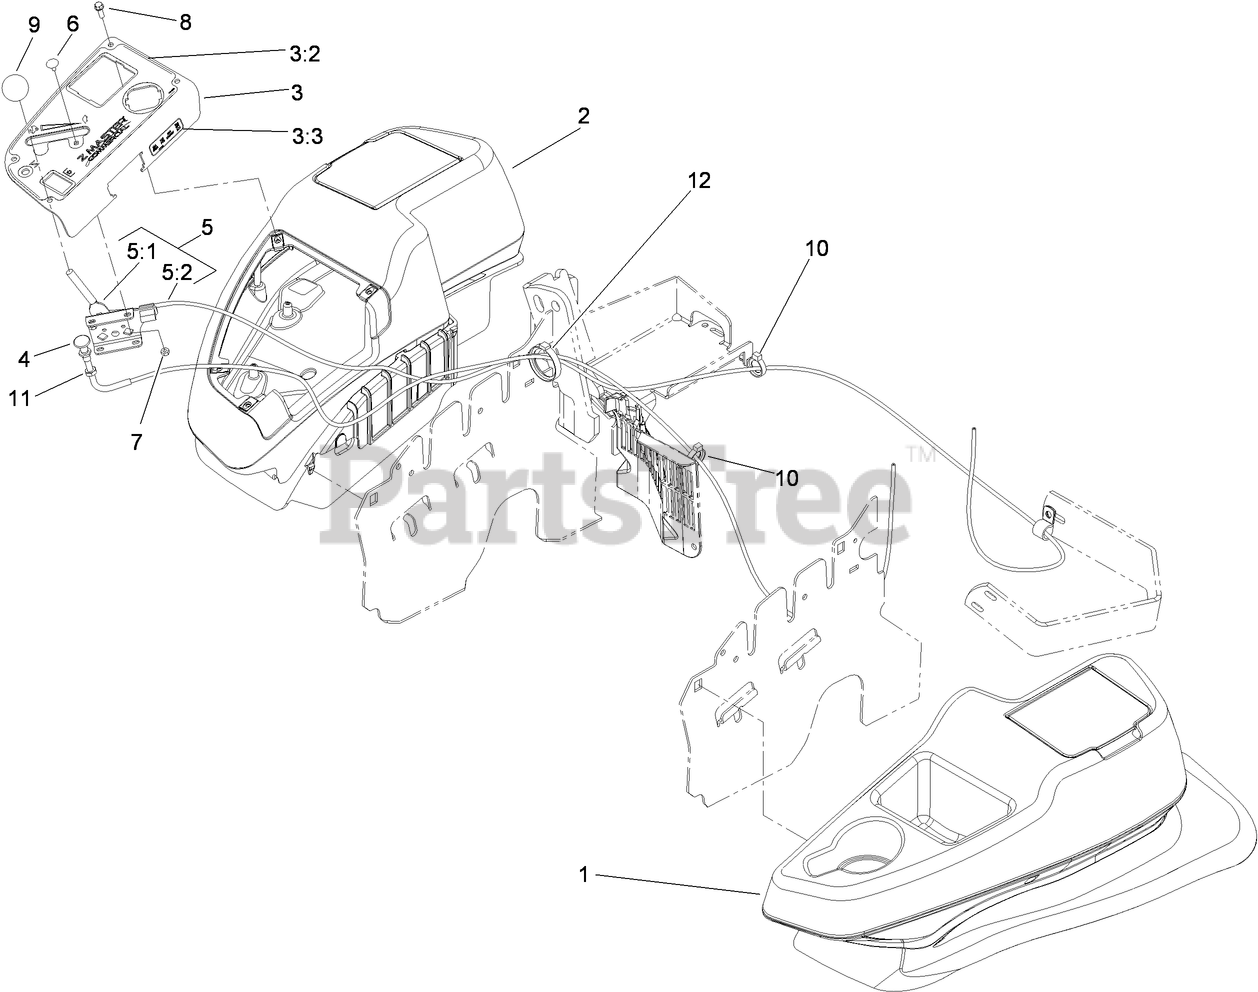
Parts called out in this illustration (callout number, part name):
1	LH CONSOLE ASM
2	RH CONSOLE ASM
3	CONTROL PANEL ASM
3:2	DECAL-PANEL, CONTROL
3:3	DECAL-FUSES
4	CHOKE CONTROL ASM
5	CONTROL-THROTTLE ASM
5:1	LEVER-THROTTLE
5:2	CABLE-THROTTLE
6	BOLT-CARR
7	NUT-LOCK, NI
8	SCREW-HWH
9	KNOB-BALL
10	CLAMP-HOSE
11	NUT-HJ
12	CLAMP-HARNESS
